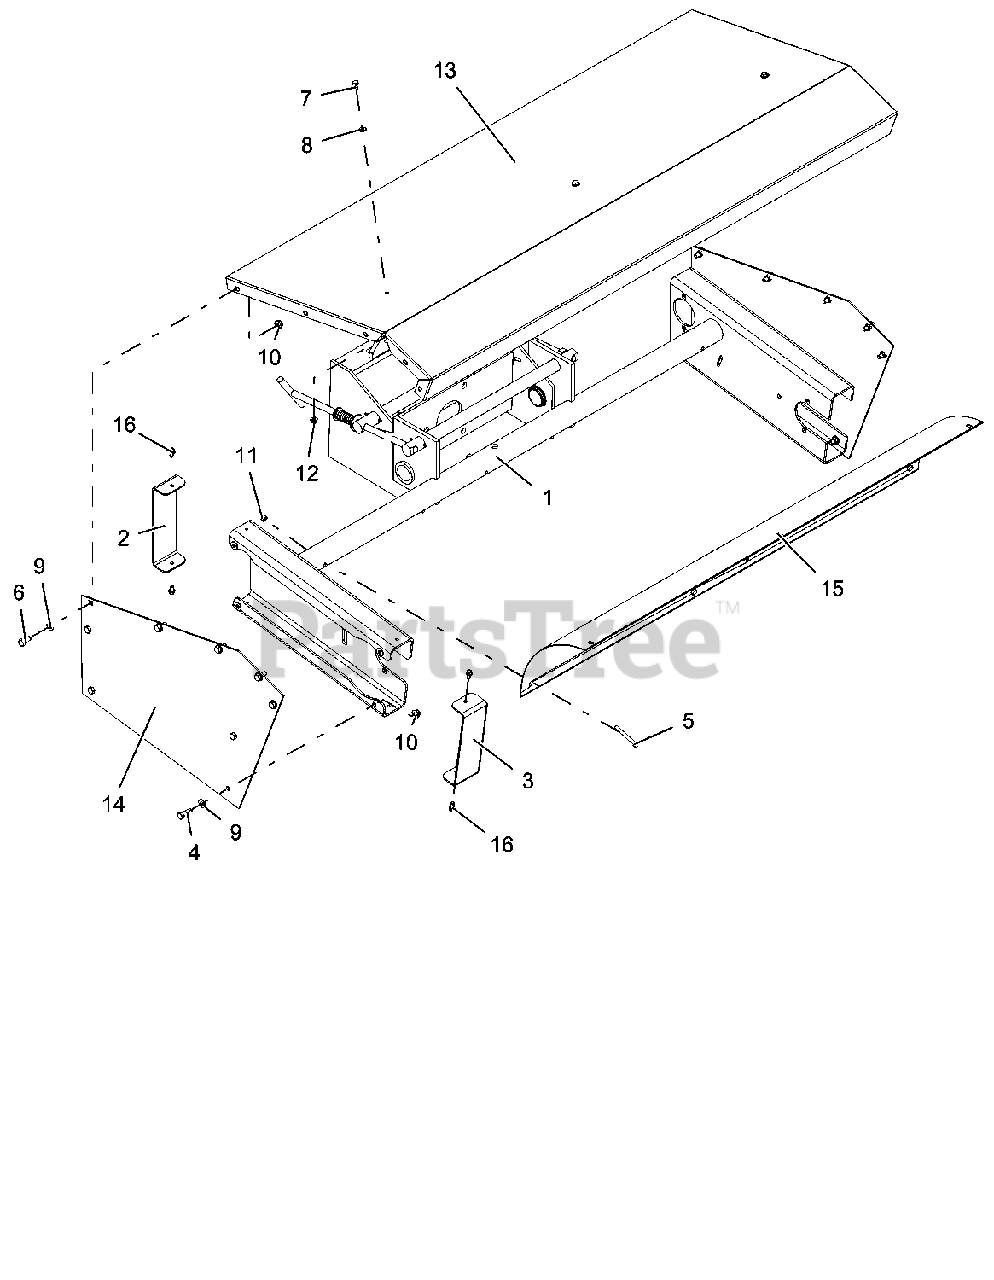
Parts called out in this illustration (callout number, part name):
1	WLDMT, BRUSH FRAME SUPPORT
2	BRUSH, BRKT COVER
3	BRUSH, BRKT COVER FRONT
4	BLT,HEX .31-18X1.00 G5ZC120
5	BLT,HEX .25-20X2.25 G5ZC120
6	BLT,HEX .31-18X.75 G5ZC120
7	BLT,HEX .25-20X.50 G5ZC120
8	WSHR,FL-STL.281X.62X.065 ZC120
9	WSHR,FL-STL.344X.688X.065ZC120
10	NUT,LK-NYL-FLG .31-18 G5ZC120
11	NUT,LK-CTR .25-20 G5ZC120
12	NUT,LK-NYL-FLG .25-20 G5ZC120
14	PLT,SIDE
16	SCR-TAP .25-20X.50 HWH ZC120
